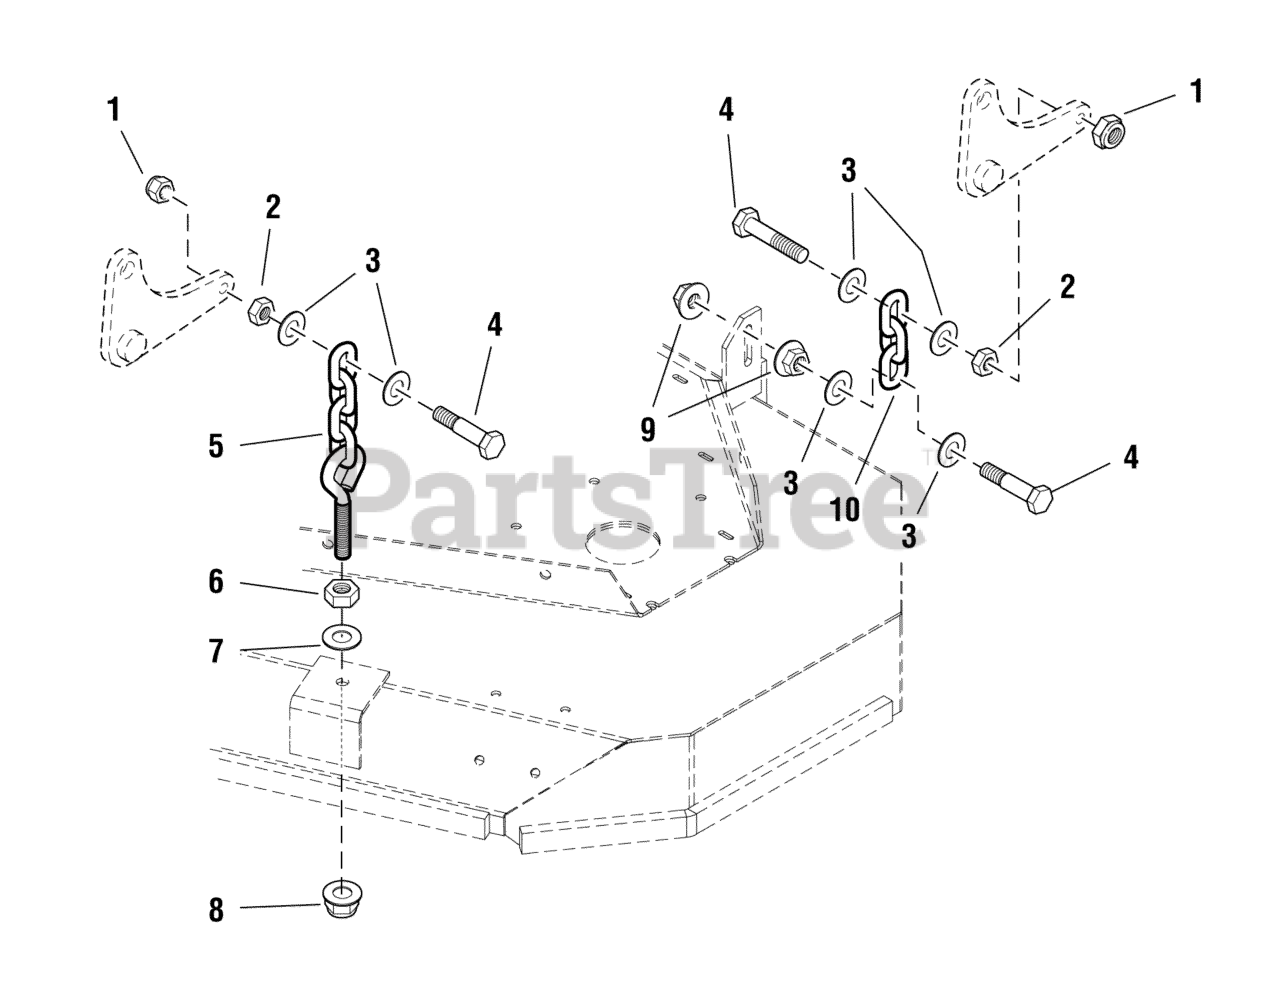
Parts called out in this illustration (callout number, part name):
1	NUT, 3/8-16 HEX NYLON LOCK
2	NUT, 3/8-16 HEX JAM
3	WASHER, 3/8 SAE
4	BOLT, 3/8-16 X 2, GD5, CZ
5	HANGER, FRONT DECK - 4 LINK, 5.5" EB
6	NUT, 1/2-13 HEX
7	WASHER, 1/2 SAE
8	NUT, 1/2-13 HEX NYLON LOCK
9	NUT, 3/8-16 HEX SERRATED FLANGE
10	CHAIN, 5/16" GD30, 3 LINKS
